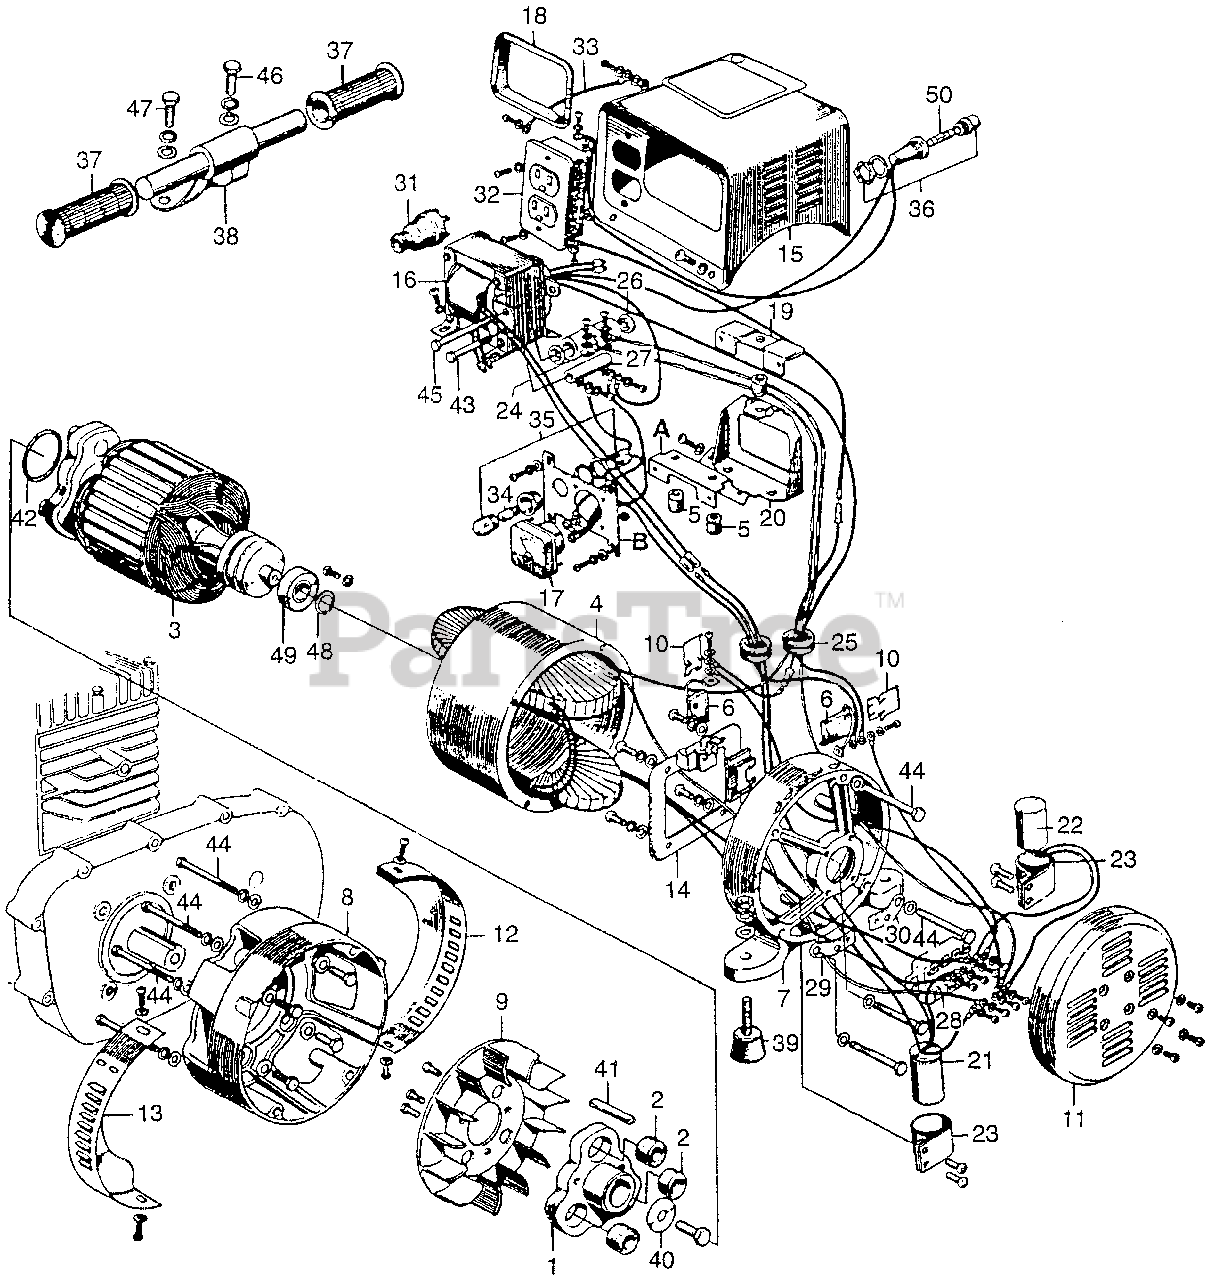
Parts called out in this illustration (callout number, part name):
1	FLANGE, COUPLING A
2	RUBBER, COUPLING
3	ROTOR ASSY.
4	STATOR ASSY. *R8* (BRIGHT RED)
5	RUBBER, FRICTION (NOT AVAILABLE)
6	BRUSH (NOT AVAILABLE)
7	COVER, END
8	COVER, FR.
9	FAN, GENERATOR
10	SPRING, BRUSH (NOT AVAILABLE)
11	COVER, CLEANER *R8* (BRIGHT RED)
12	PROTECTOR A, GENERATOR FAN *R8* (BRIGHT RED)
13	PROTECTOR B, GENERATOR FAN *R8* (BRIGHT RED)
14	PLATE ASSY., RIG
15	PANEL, CONTROL *R8* (BRIGHT RED)
16	TRANSFORMER, CURRENT
19	PANEL, METER
20	BASE, MOUNT
21	CONDENSER A
22	CONDENSER B
24	RESISTOR, RF
25	GROMMET, WIRE
26	WASHER, RESISTOR
27	RESISTOR, RP
28	STACK, DIODE (NOT AVAILABLE)
29	HOLDER, DIODE A
30	HOLDER, DIODE B
31	PLUG ASSY., RECEPTACLE
32	RECEPTACLE
33	WIRE, GROUND
34	BULB (24V2W)
35	SOCKET ASSY., PILOT LAMP (NOT AVAILABLE)
36	HOLDER, FUSE (NOT AVAILABLE)
37	GRIP B, L. HANDLEBAR
38	HANDLE, CARRYING
39	RUBBER, GENERATOR (LOWER) (NOT AVAILABLE)
40	WASHER (8MM)
41	KEY (7X7X33)
42	O-RING (35.5X3) (NOK)
43	BOLT, HEX. (5X55) (NOT AVAILABLE)
44	BOLT, HEX. (6X55)
45	BOLT, HEX. (6X82) (SOURCE: VINTAGE PARTS INC.)
46	BOLT, HEX. (8X14)
47	BOLT, HEX. (8X22)
48	CIRCLIP (OUTER) (17MM)
49	BEARING, RADIAL BALL (6203UU)
50	FUSE A (15A)
